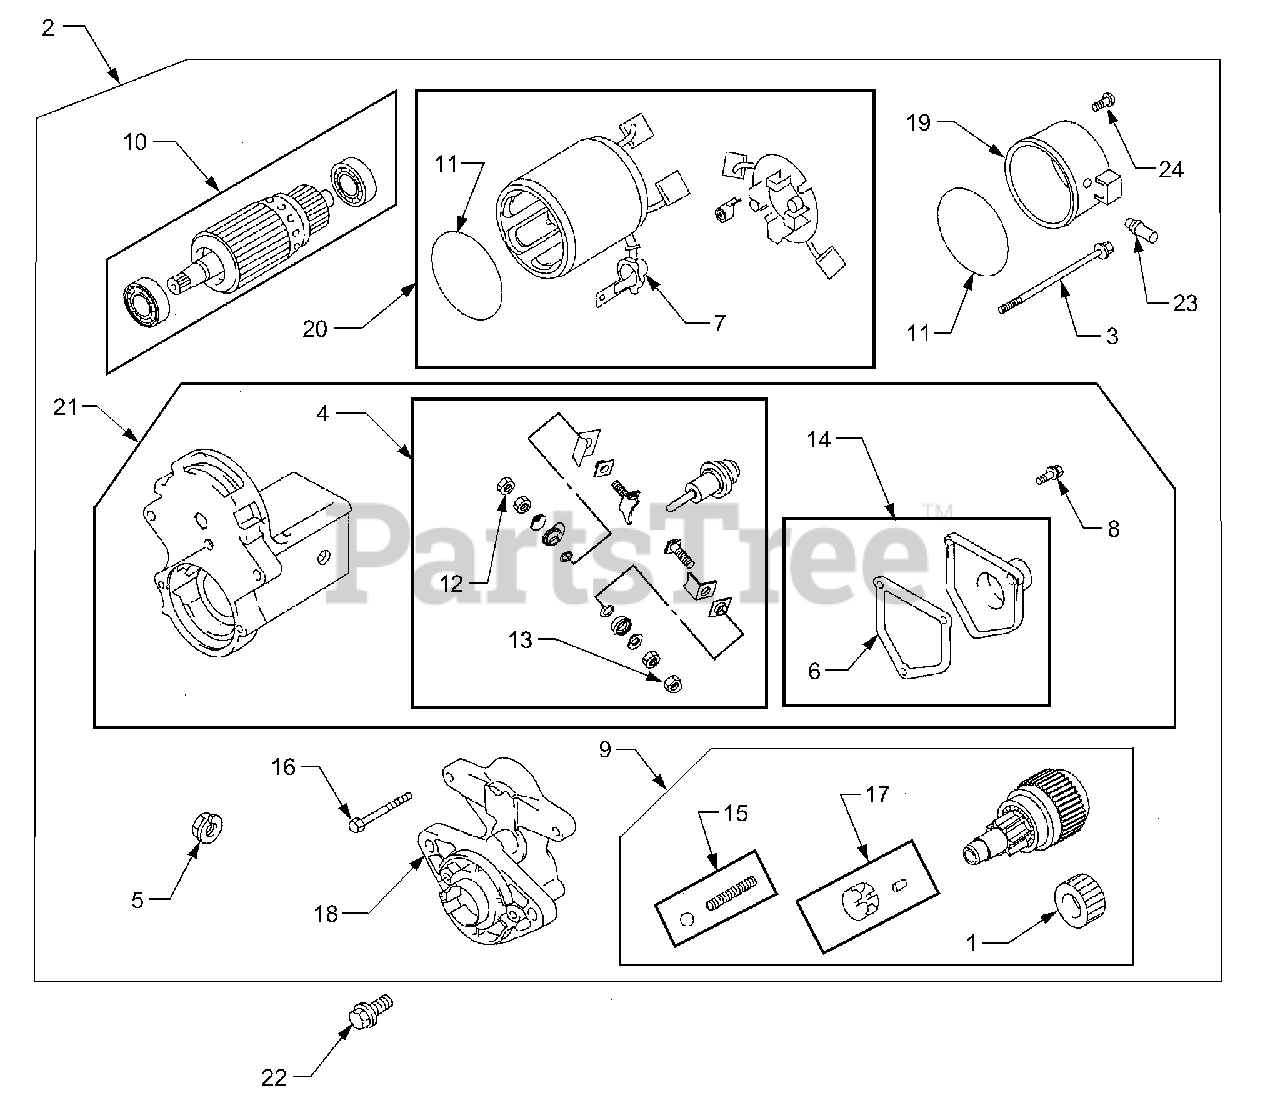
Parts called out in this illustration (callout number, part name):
1	Gear, Starter Drive
2	Motor, Starter
3	Screw, Starter Motor
4	Terminal Kit, Solenoid
5	Nut, Starter Motor Terminal
6	Gasket, Solenoid Cover
7	Boot, Terminal
8	Screw, Solenoid Cover
9	Drive, Starter
11	Seal, O-Ring
12	Nut, Solenoid Terminal
13	Nut, Solenoid Terminal
14	Cover, Solenoid
15	Spring, Detent
16	Screw, Drive Cap
17	Clutch Roller
18	Cap, Drive
20	Housing, Starter
21	Solenoid, Starter
22	Screw, Starter Motor
23	Plug, Vent
24	Screw, End Cap
